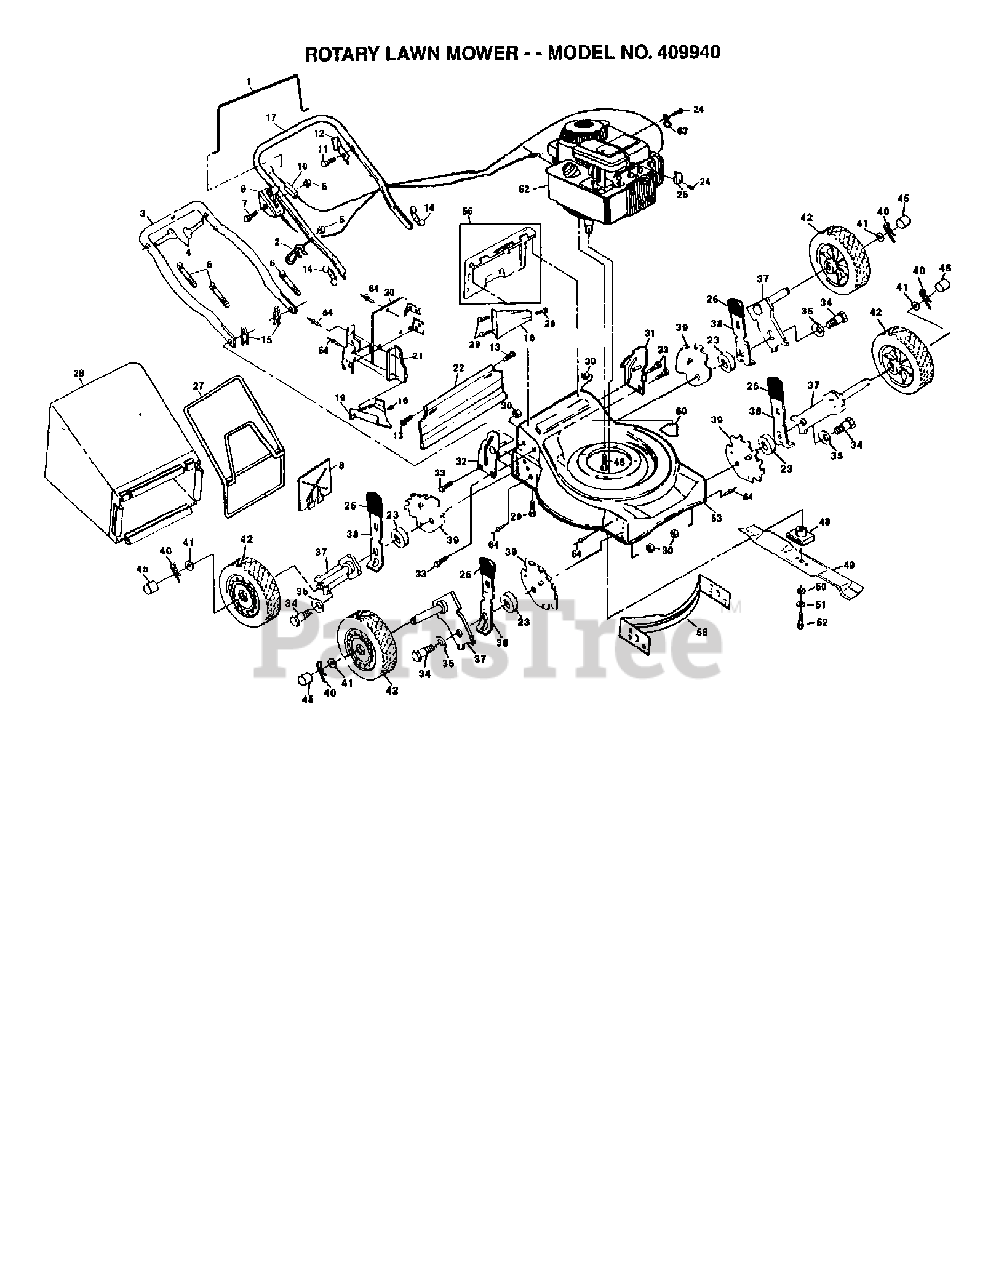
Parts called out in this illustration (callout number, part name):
1	CONTROL BAR
4	HANDL BOLT
6	TIE GUIDE
7	MACHINE SCREW 1/4-20X2-1/4
8	Mulcher Plate
10	CABLE.MZR.51.RT.SP./PU.
11	TAPPING SCREW
12	Poulan TBD
13	HINGE SCREW
14	NUT WING PM
15	HAIRPIN COTTER
16	SCREW PM
17	UPPER HANDLE
18	REAR BAFFLE
19	DISCHARGE BAFFLE
20	BACK PLATE
21	SIDE BAFFLE
22	REAR SKIRT
24	SCREW.HEX.HEAD.WASHER.10-16
28	Poulan TBD
31	HANDLE BRACKET
32	HANDLE BRACKET
33	SCREW
34	SHOULDER BOLT PM
35	WASHER.BELLEVILLE
37	AXLE ARM
38	SELECTOR SPRING
39	WHEEL ADJUSTING BRACKET
40	RETAINER CLIP PM
41	WASHER
42	WHEEL & TIRE ASSEMBLY
48	BLADE ADAPTOR
49	BLADE 20" MULCH
50	WASHER,HARDEN
52	SCREW, HEX HD 3/8-24 X 1-3/8
53	Poulan TBD
56	REAR DOOR KIT
58	FRONT BAFFLE
60	DECAL NLA
63	GUIDE CLIP PM
64	RIVET BLIND
